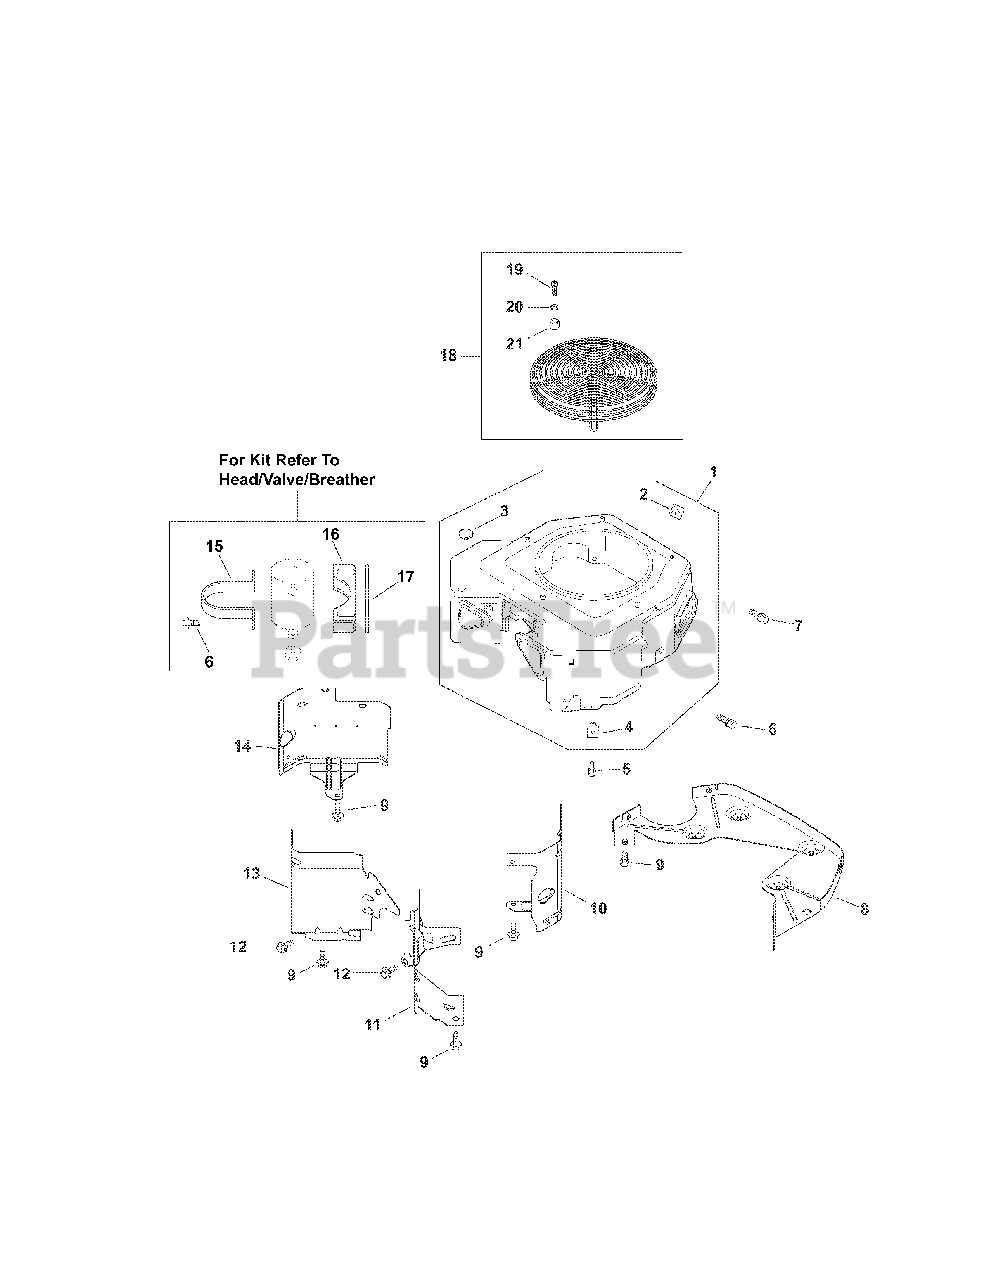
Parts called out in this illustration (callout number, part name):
1	Housing assembly, blower
2	Nut, plastic
3	Plug, button 9/16
4	Nut, plastic
5	Screw, flg thd frm M5x0.8x20
6	Screw, flg thd frm M5x0.8x16
7	Screw, flg thd frm M5x0.8x16
8	Plate, backing (Includes KH-25-154-11-S)
9	Screw, flg thd frm M6x1.0x16
10	Baffle, cyl barrel #2 side
11	Baffle, valley #2 side
12	Screw, flg thd frm M5x0.8x10
13	Baffle, valley #1 side
14	Baffle, cyl barrel #1 side
15	Strap, breather
16	Bracket, breather separator
18	Kit, guard (Includes 19-21& KH-24-332-01-S)
19	Screw, 6 lbd skt pan M5x0.8x15
20	Washer, flat 7/32 inch
21	Spacer
